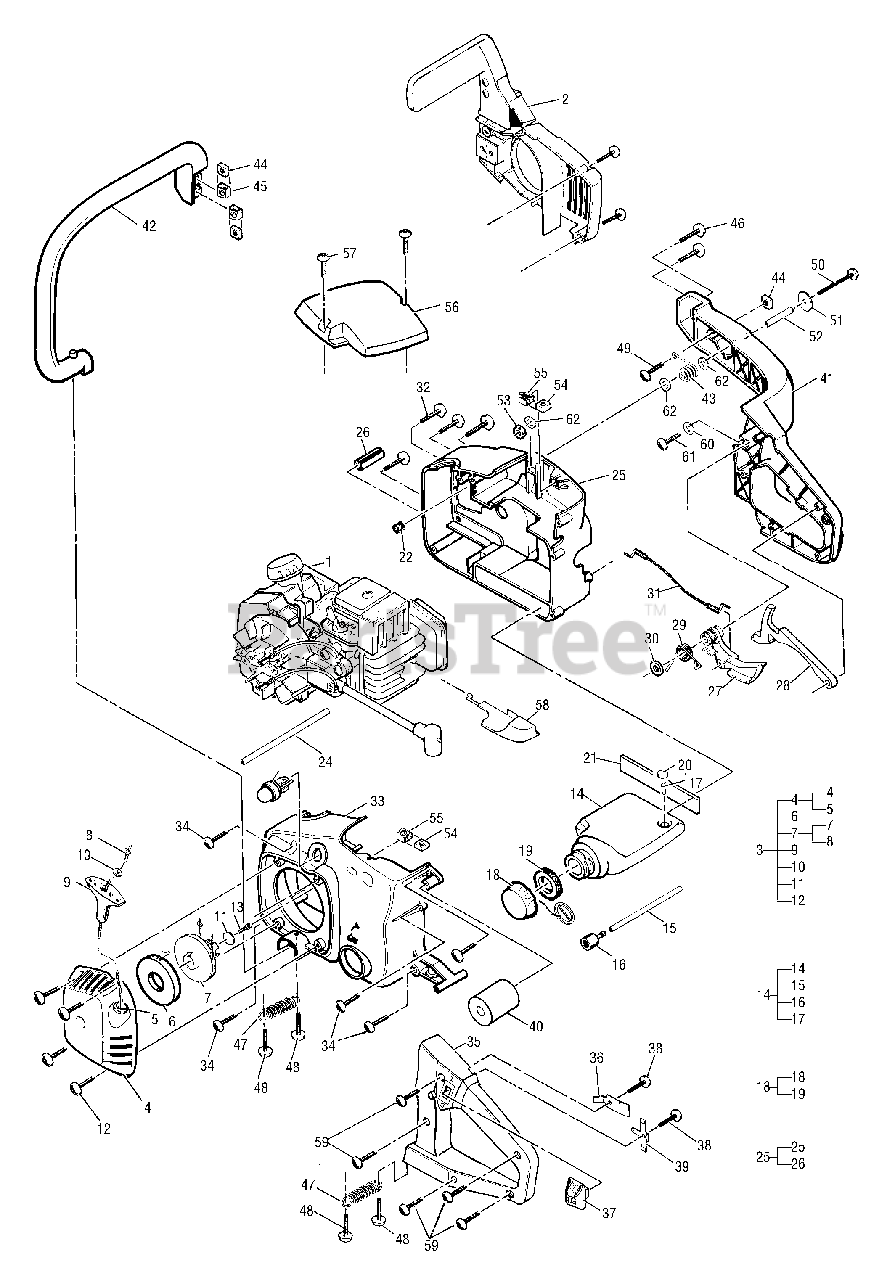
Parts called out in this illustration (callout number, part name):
1	Powerhead Asy
2	Chain Brake Asy
3	Starter Housing Asy, Yellow
4	Housing/Rope Guide Asy, Yellow
5	Rope Guide
6	Spring, Starter Rewind
7	Rope/Drum Asy (32cc)
8	Rope, Starter 50 inch
9	Handle, Starter
10	Bushing, Starter
11	Washer, .19 ID x .68 OD
12	Screw, 8-16 x .75 Torx Hd Plast
13	Screw, 8-16 x .75 Torx Hd Plastite
14	Oil Tank Asy
15	Hose, Oil Pick-up
16	Filter, Oil
17	Valve, Duckbill
18	Oil Cap Asy
19	Gasket
20	Filter, Foam
21	Spacer, Oil Tank
22	Filter, Foam
23	Primer, Remote
25	Housing/Pin Asy, Right
26	Pin, Roll 1/4 x 1.0 L
27	Trigger, Throttle
28	Latch, Throttle
29	Spring, Torsional
30	"O" Ring
31	Cable, Throttle
32	Screw, 10-24 x .62 Tr Hd Torx
33	Engine Housing, Left, AV, Blk
34	Screw, 8-16 x .75 Tr Hd, Plastite
35	Handle, Left Rear, Black, AV
36	Contact, Ground Stud, AV
37	Button,Stop Switch
38	Screw, 8-16 Plastite
39	Contact, Ignition
40	Isolator, Rubber
41	Handle, Right Rear, Black
42	Handle, Front
43	Spring, Extension
44	Nut, Square 10-24
45	Retainer, Nut
46	Screw, 10-24 x .62 Tr Hd Torx
47	Spring, Extension
48	Screw, 8-16 x .75 Tr hd Plastite
49	Screw, 10-24 x .50 Tr Tors
50	Screw, 10-24 x 2.0 Tr Torx
51	Washer, 2.0 x 7.8 in. OD
52	Spacer, 0.2 ID x 1.0 Lg
53	Nut, Hex Lock 10-24
54	Nut, Square 10-24
55	Retainer, Nut
56	Cover, Air Filter
57	Screw, 10-24 x .625 Pn Hd Torx
58	Rod, Choke
59	Screw, 8-16 x .75 Tr Hd Plastite
60	Washer, .19 ID x .68 OD
61	Screw, 8-16 x .75 Tr Hd Plastite
62	Washer, .469 OD x .222 ID
